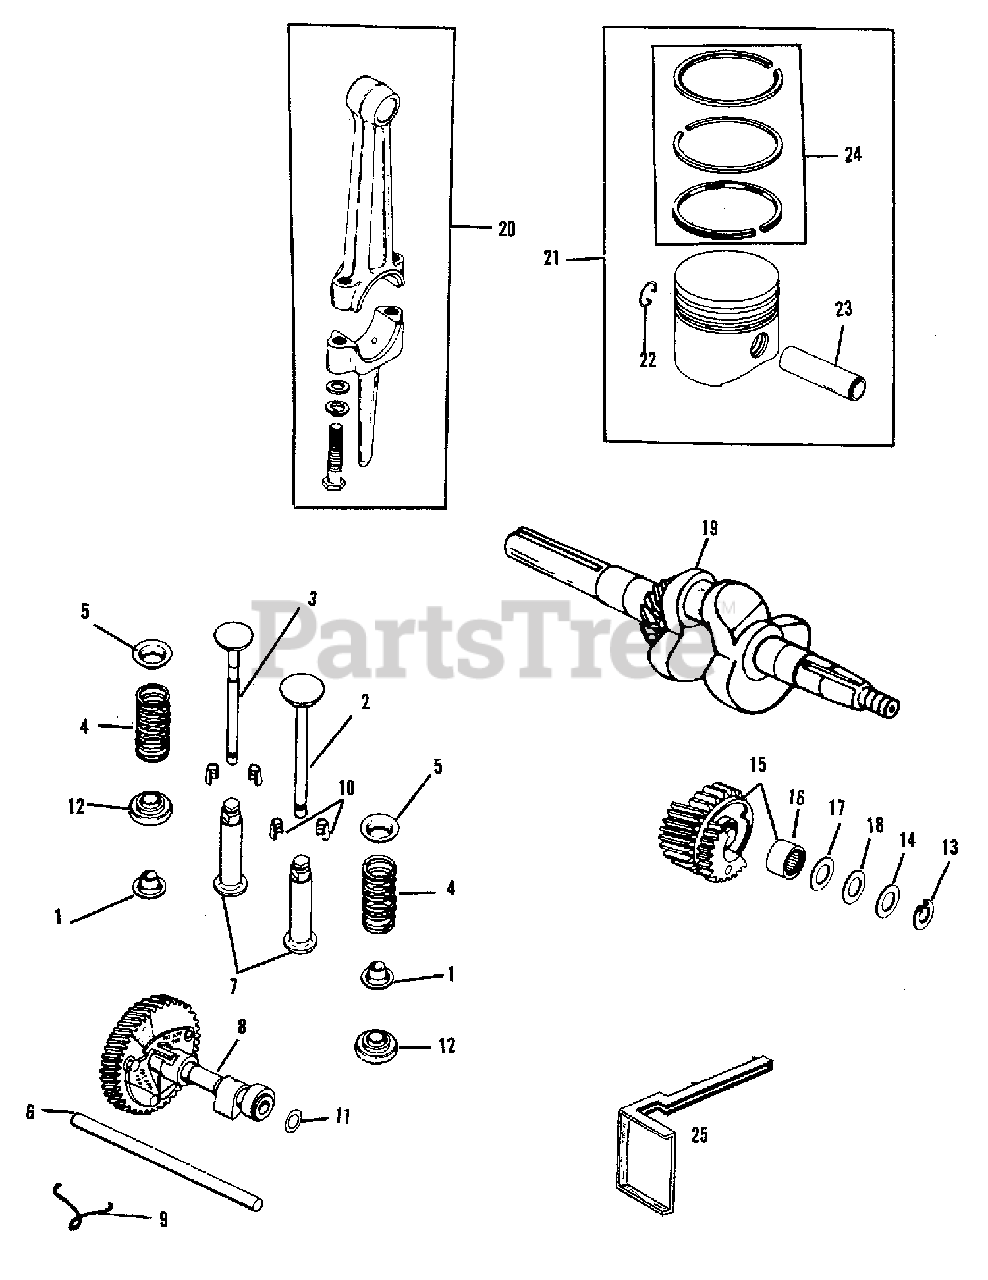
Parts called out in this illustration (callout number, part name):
1	RETAINER, Valve Spring
2	VALVE, Intake (10 & 12 H.P. Engines)
2	VALVE, Intake (14 H.P. Engine)
3	VALVE, Exhaust (10 & 12 H.P. Engines)
3	VALVE, Exhaust (14 H.P. Engine)
4	SPRING, Valve, (10 & 12 H.P. Engines)
4	SPRING, Valve, (14 H.P. Engine)
5	RETAINER, Upper Spring
6	PIN, Camshaft
7	TAPPET ASSEMBLY
8	CAMSHAFT ASSEMBLY (Includes SPRING)
9	SPRING, Actuating
10	KEEPER, Valve Keeper (In Pairs)
11	SPACER, Camshaft .005 (Use as Required)
11	SPACER, Camshaft .010 (Use as Required)
12	ROTATOR, VALVE
15	GEAR ASSEMBLY (Includes Item 16)
16	BEARING, Needle
17	SPACER (Use as Required)
19	CRANKSHAFT (10 H.P. Engine)
19	CRANKSHAFT (12 H.P. Engine)
19	CRANKSHAFT (14 H.P. Engine)
19	KEY, Crankshaft
20	ROD ASSEMBLY, Connecting (Standard) (10 H.P. Engine)
20	ROD ASSEMBLY, Connecting (.010) (10 H.P. Engine)
20	LOCKWASHER, 3/8
20	ROD ASSEMBLY, Connecting (Standard) (12 & 14 H.P. Engines)
20	ROD ASSEMBLY, Connecting (.010) (12 & 14 H.P. Engines)
20	LOCKWASHER, 5/16
21	PISTON ASSEMBLY, Standard 10 H.P. Engine
21	PISTON ASSEMBLY, .010 10 H.P. Engine
21	PISTON ASSEMBLY, .020 10 H.P. Engine
21	PISTON ASSEMBLY, .030 10 H.P. Engine
21	PISTON ASSEMBLY, Standard 12 H.P. Engine
21	PISTON ASSEMBLY, .010 12 H.P. Engine
21	PISTON ASSEMBLY, .020 12 H.P. Engine
21	PISTON ASSEMBLY, .030 12 H.P. Engine
21	PISTON ASSEMBLY, Standard 14 H.P. Engine
21	PISTON ASSEMBLY, .010 14 H.P. Engine
21	PISTON ASSEMBLY, .020 14 H.P. Engine
21	PISTON ASSEMBLY, .030 14 H.P. Engine
22	RETAINER, Piston Pin
23	PIN, Piston
24	RING SET, Standard 10 H.P. Engine
24	RING SET, .010 10 H.P. Engine
24	RING SET, .020 10 H.P. Engine
24	RING SET, .030 10 H.P. Engine
24	RING SET, Standard 12 H.P. Engine
24	RING SET, .010 12 H.P. Engine
24	RING SET, .020 12 H.P. Engine
24	RING SET, .030 12 H.P. Engine
24	RING SET, Standard 14 H.P. Engine
24	RING SET, .010 14 H.P. Engine
24	RING SET, .020 14 H.P. Engine
24	RING SET, .030 14 H.P. Engine
25	TOOL, Gauge (For Balance Weights On Crankshaft Gear)
